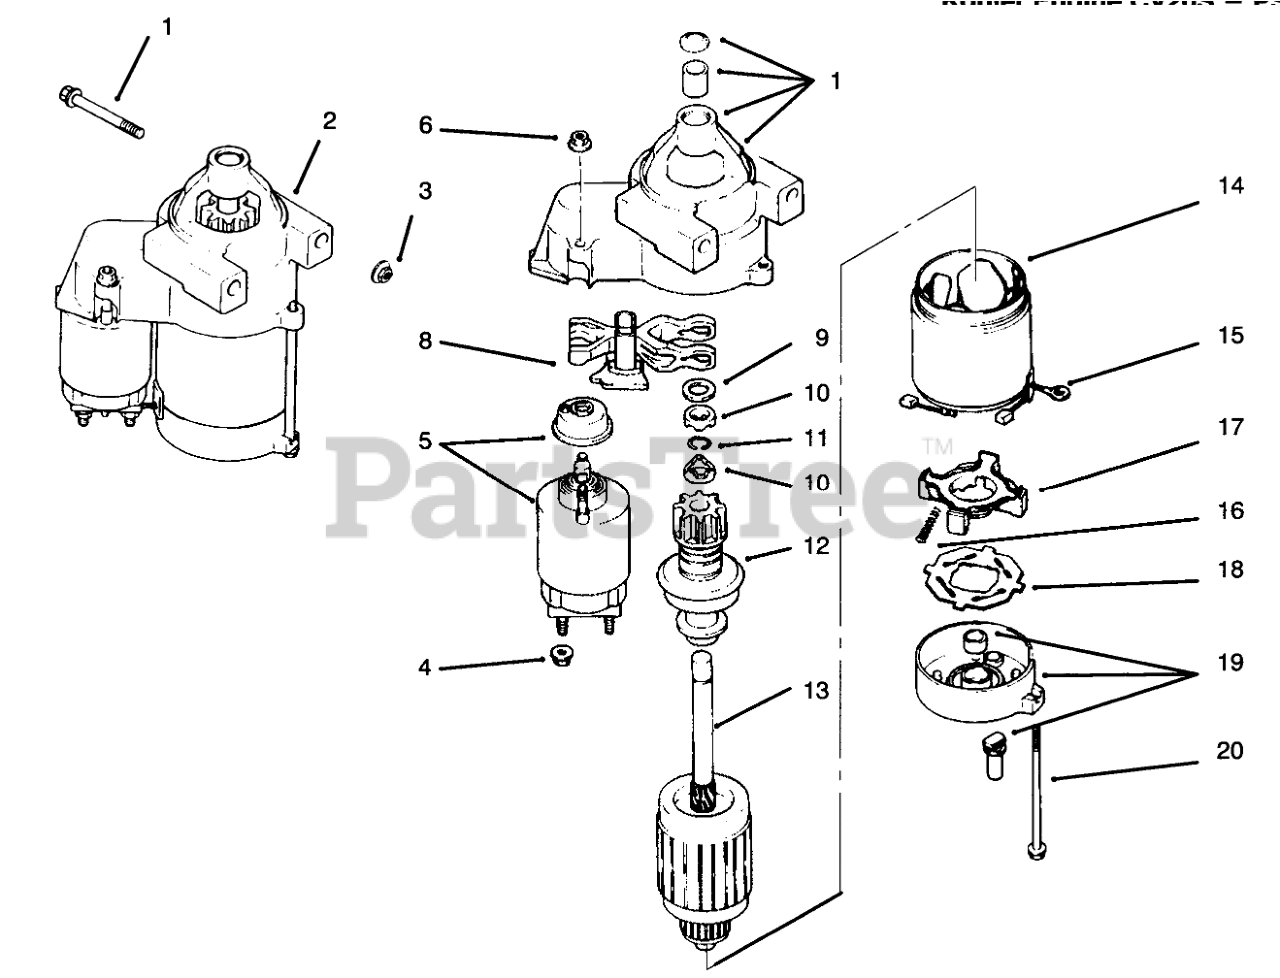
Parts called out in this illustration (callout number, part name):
2	Starter Solenoid Shift (Incl. Ref. #4-20)
3	Nut
4	Nut Starter
5	Cap-Drive End
7	Solenoid
8	Lever Starter Drive
9	Washer-Thrust
10	Nut-Stop Collar
11	Ring-Retainer
12	Drive-Pinion
13	Armature-Starter
15	Kit-Brush (Incl. Ref. #16)
16	Spring-Brush
17	Holder-Brush
18	Insulator
19	Cap-Commutator End
